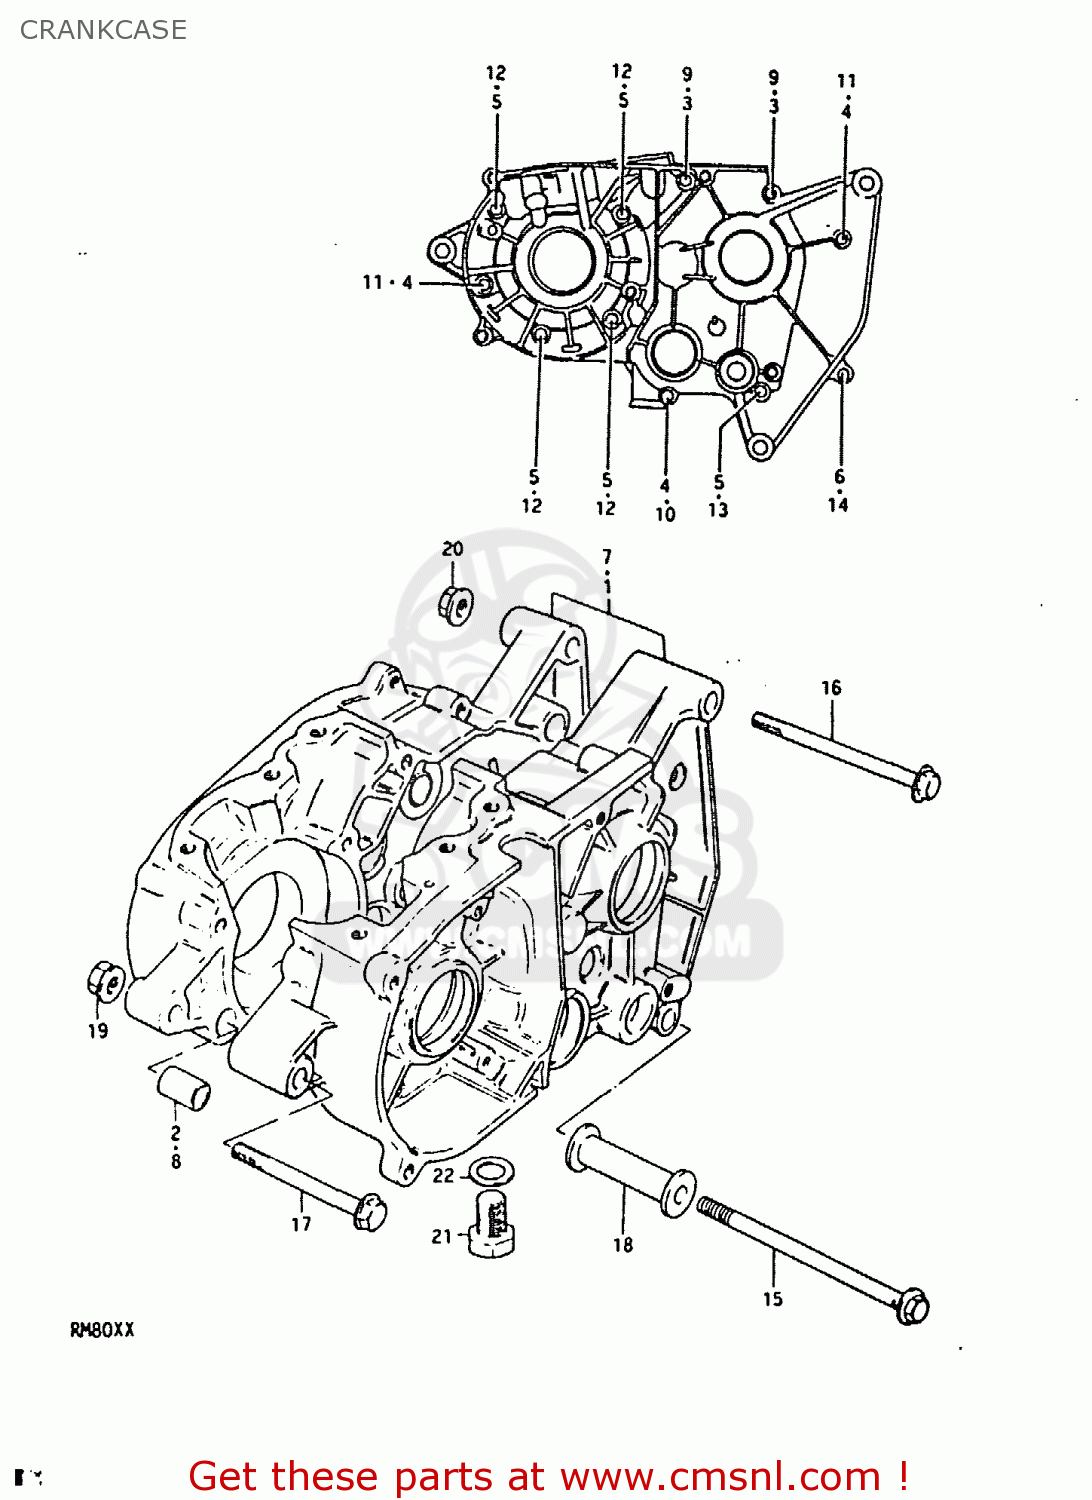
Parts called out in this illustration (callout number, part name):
1	CRANKCASE SET
2	PIN
3	CROSS SCREW (6 X 75)
4	SCREW
5	SCREW (6X35)
6	SCREW
7	CRANKCASE SET
8	PIN
9	CROSS SCREW (6 X 75)
10	SCREW
11	SCREW
12	SCREW (6X45)
13	SCREW (6X35)
14	SCREW
15	BOLT 10X250
16	BOLT
17	BOLT 8X75
18	SPACER,ENGINE MOUNTING
19	NUT
20	NUT
21	BOLT 10X20
22	GASKET(10X14X3.6) (NAS)
